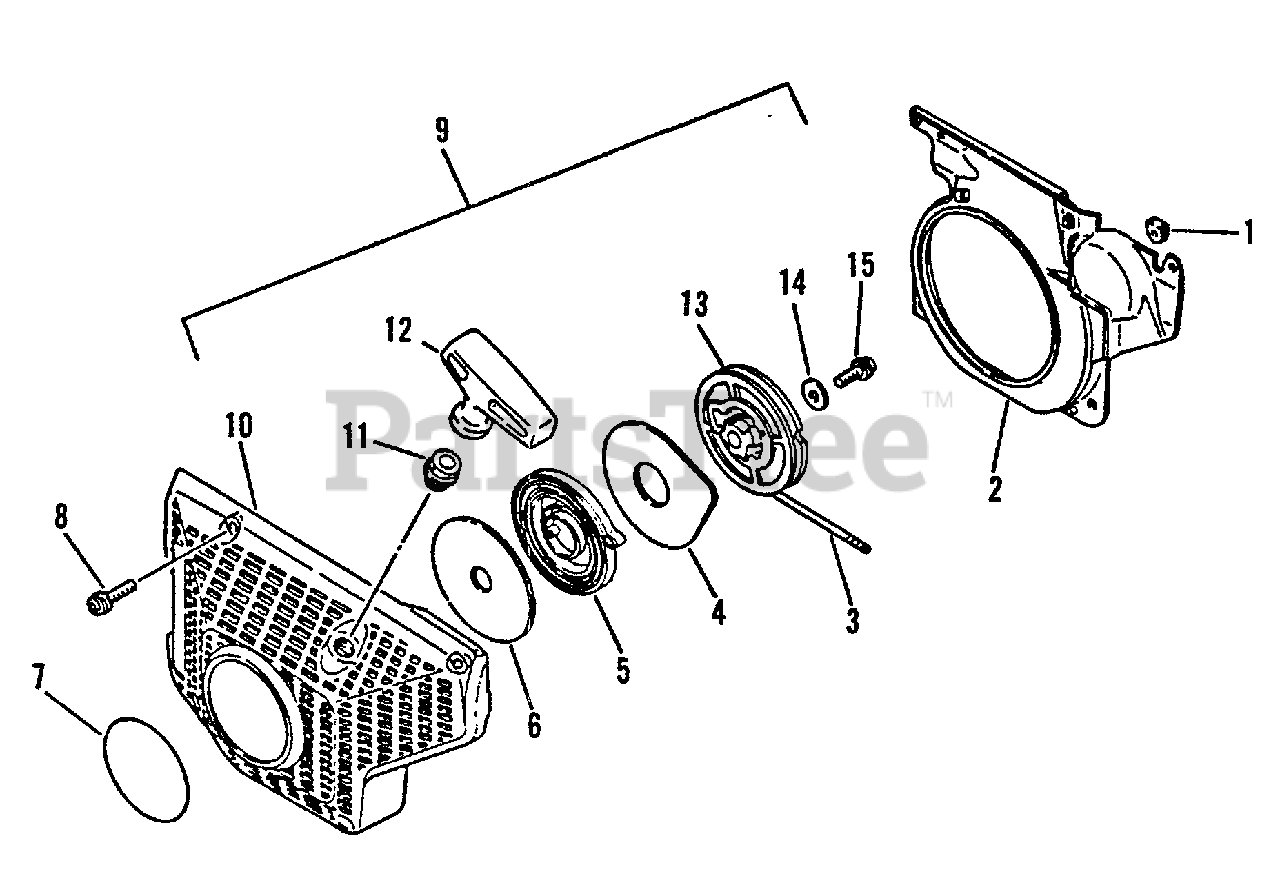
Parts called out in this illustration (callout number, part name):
2	SHIELD, FAN
3	ROPE, STARTER - 3.5X960
4	PLATE, STARTER
5	SPRING, REWIND
6	PLATE, STARTER
7	LABEL - ECHO
8	SCREW - 5X20
9	STARTER ASSY
10	CASE, STARTER
11	GUIDE, ROPE
12	GRIP, STARTER
13	REEL, ROPE
14	WASHER - 5
15	SCREW - 5X14
